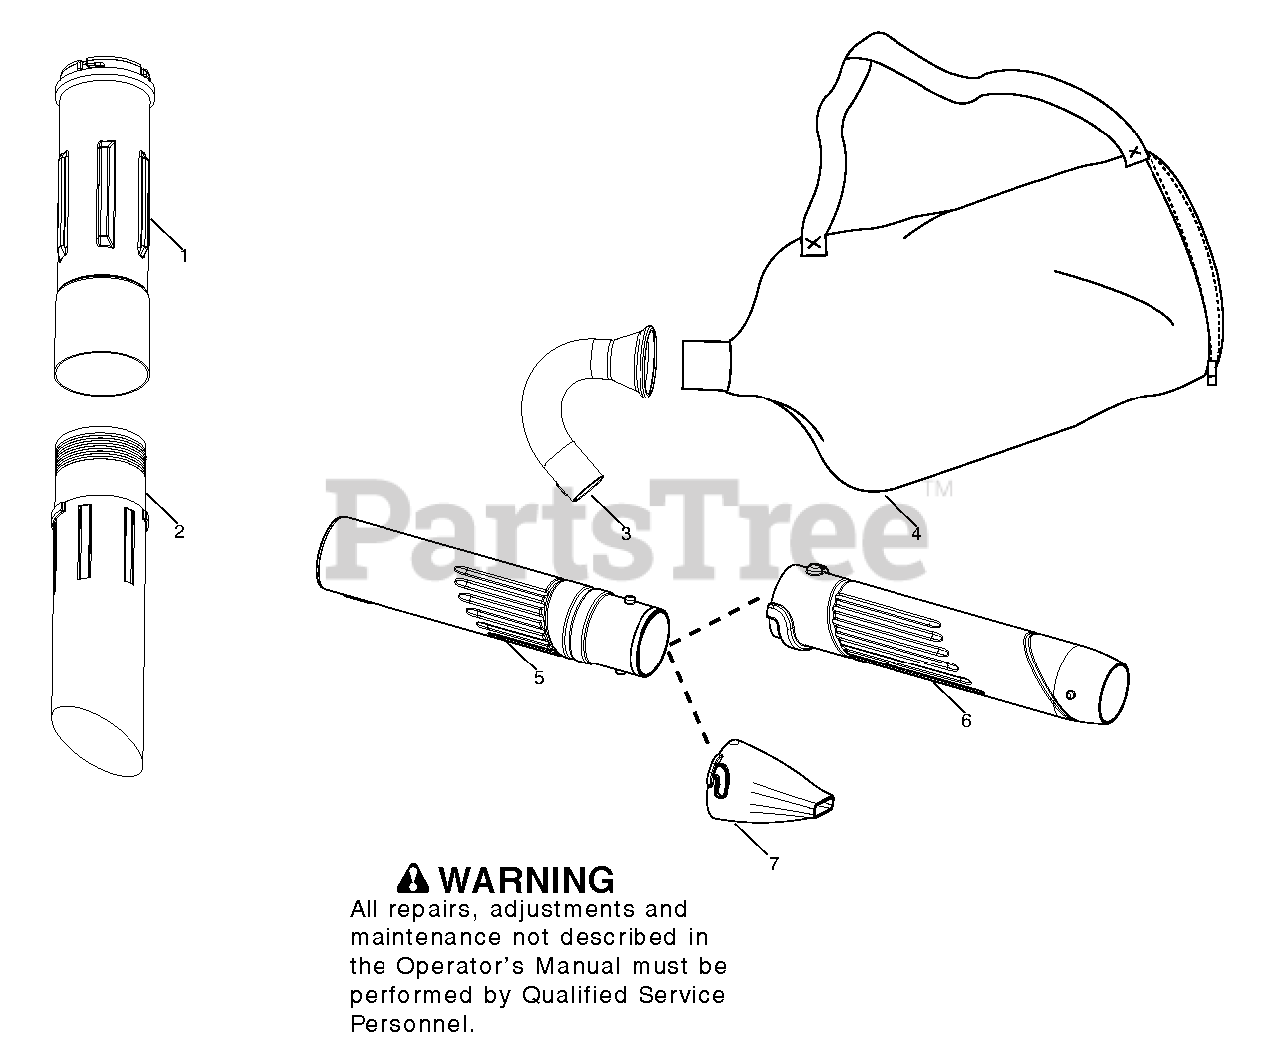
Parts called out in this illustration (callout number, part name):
1	TUBE VAC UPPER BLACK
2	TUBE LOWER VAC
4	ASSY VAC BAG GAS W/STRAP
5	TUBE BLOWER UPPER P/S
6	TUBE BLOWER LOWER ROUND P/S
7	NOZZLE BLACK HI SPEED ADAPTOR
